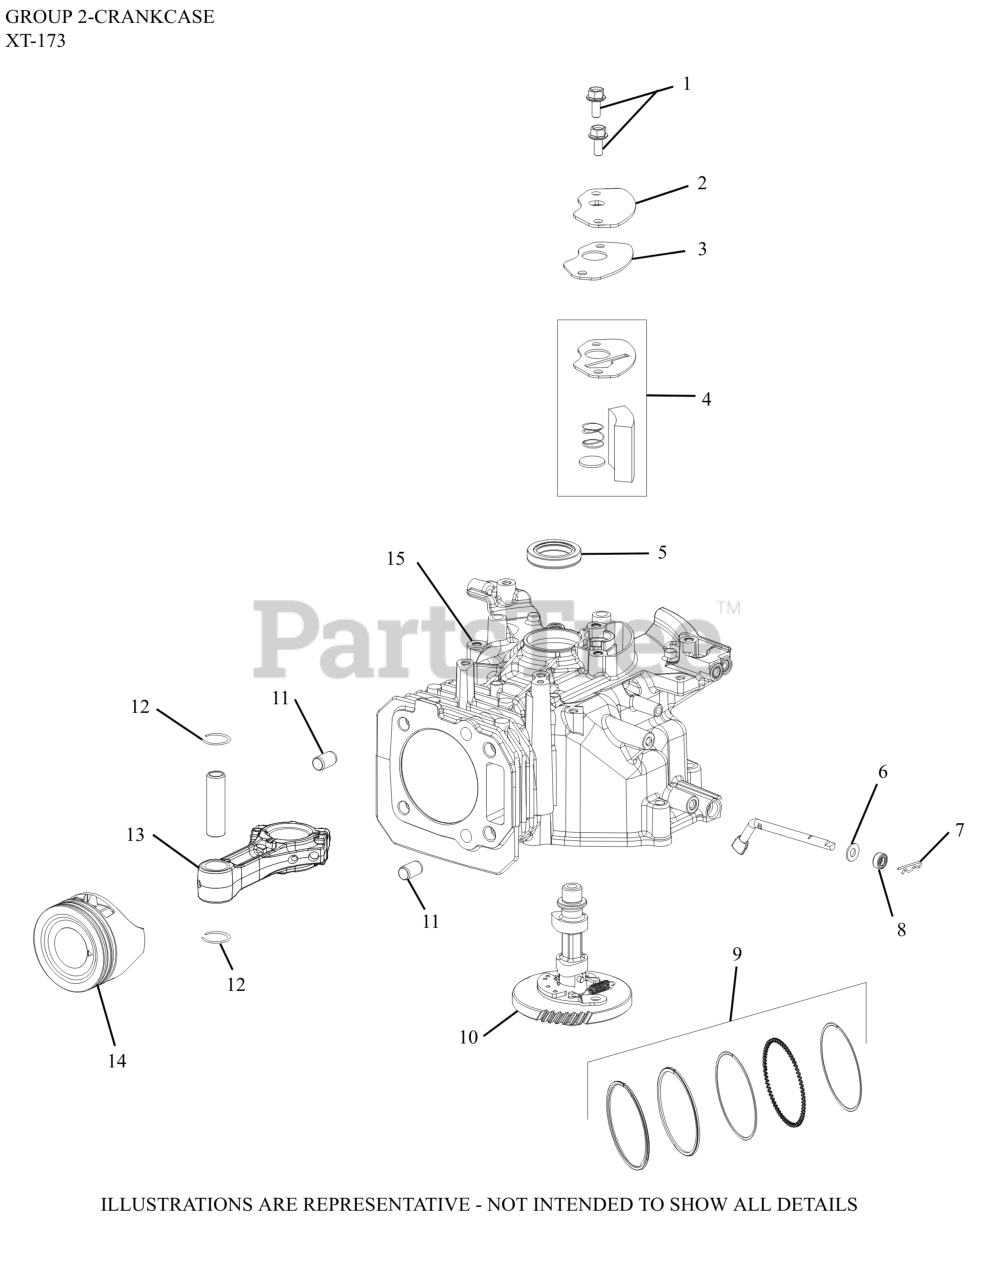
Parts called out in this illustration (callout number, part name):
1	SCREW, HEX FLANGE (M6)-USE 25 086 433-S
2	COVER, BREATHER - (#14096125S)
4	KIT, BREATHER FILTER
5	SEAL, CCASE/FLYWHEEL
6	WASHER, FLAT (DIA 13MM O.D.)-(#1446830S)
7	CLIP, GOVERNOR SHAFT
8	SEAL, OIL
10	CAMSHAFT ASSEMBLY-(#1401013S)
12	RETAINER, PISTON PIN
13	CONNECTING ROD
15	CRANKCASE- (#DSC)
NI	SHAFT, GOVERNOR CROSS
NI	PIN, PISTON
NI	PIN, DOWEL (8MM)
NI	KIT, PISTON
NI	SCREW, HEX FLANGE (M7)
